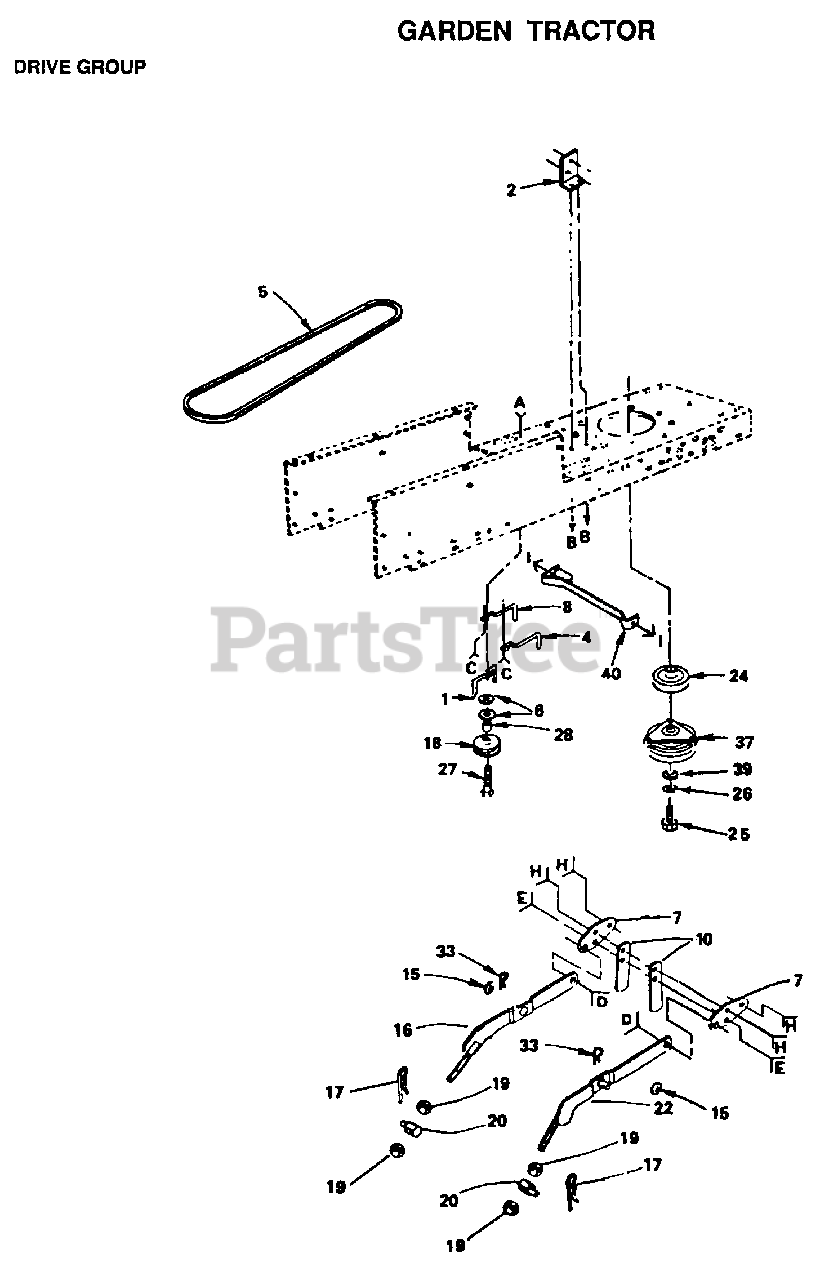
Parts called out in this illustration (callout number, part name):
2	BRACKET LT
4	"KEEPER,BLT ENG LT"
5	BELT.GRDRV.94.75
6	WASHER
7	"BRACKET, SUSPE T"
8	KEEPER BELT ENGLH
10	UPSTOP
16	LH SUSP ARM ASM
17	SPRING H
18	PULLEY.IDLER.FLAT
19	NUT
22	RH SUSP ARM ASM
26	LOCKWASHER
27	BOLT
28	SPACER T
33	SPRING.RETAINER
39	WASHER
